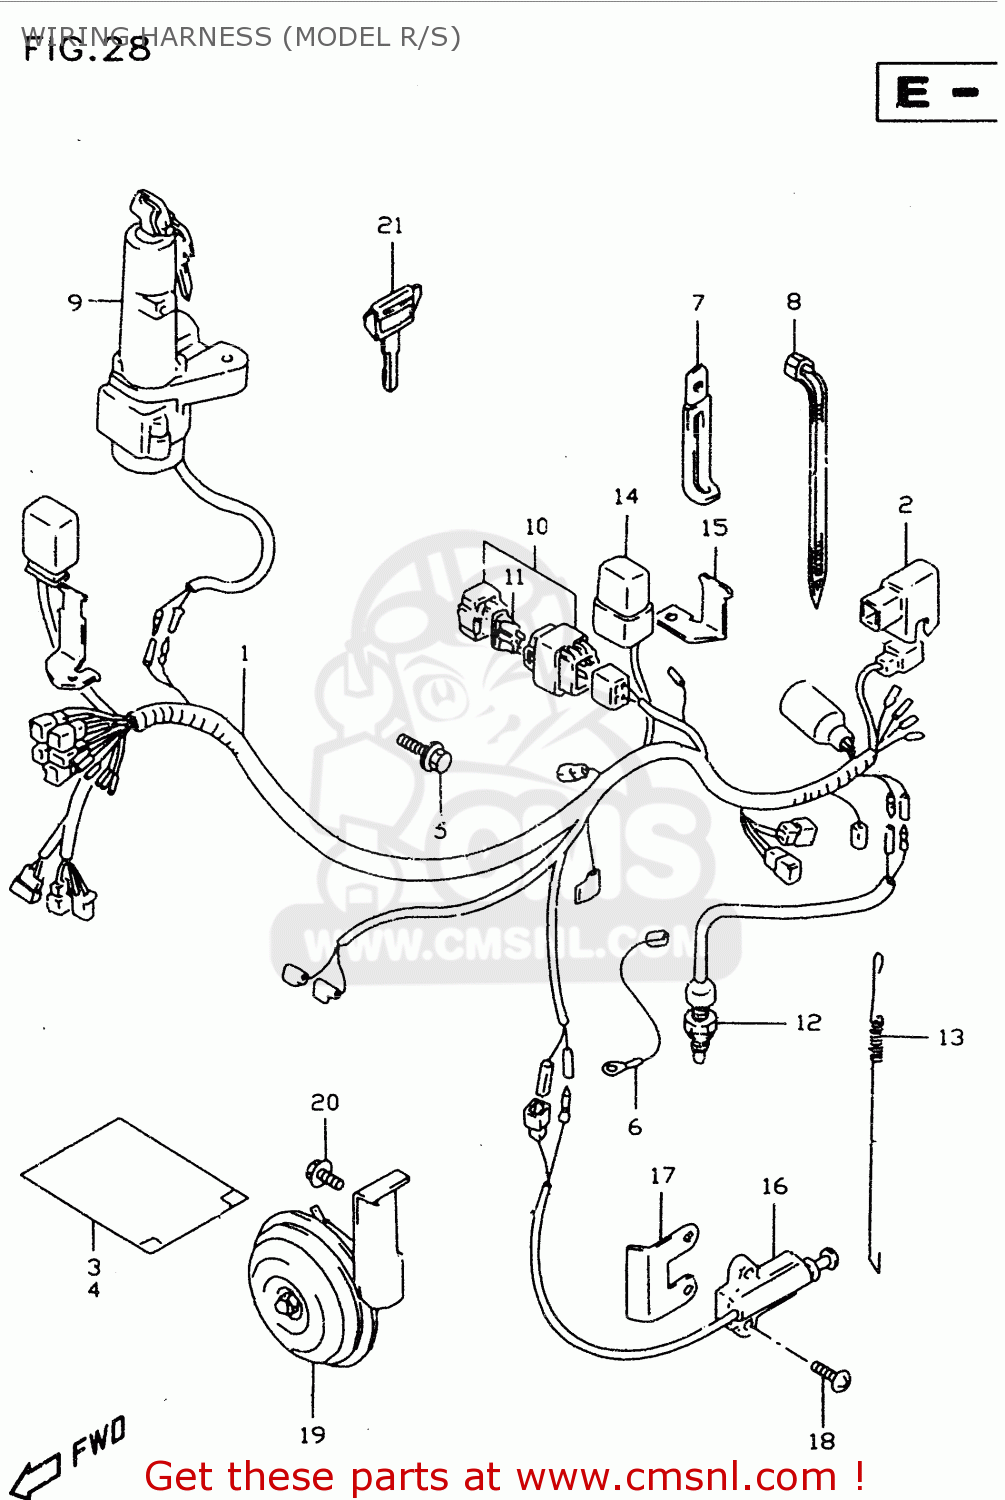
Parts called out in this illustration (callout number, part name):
1	HARNESS,WIRING
2	CAP,BATTERY PLUS
3	COVER,WIRING HARNESS
4	COVER,WIRING HARNESS
5	BOLT
6	WIRE,REGULATOR EARTH LEAD
7	CLAMP
8	CLAMP(L:33)
9	SWITCH ASSEMBLY,IGNITION
10	BOX ASSY,FUSE
11	FUSE(20A)
12	SWITCH ASSY,STOP LAMP
13	SPRING
14	RELAY ASSY
15	BRACKET,FUSE
16	SWITCH ASSY,SIDE STAND WARNING
17	PROTECTOR,SIDE STAND SWITCH
18	SCREW
19	HORN ASSY
20	BOLT
21	KEY,BLANK(TYPE:C)
